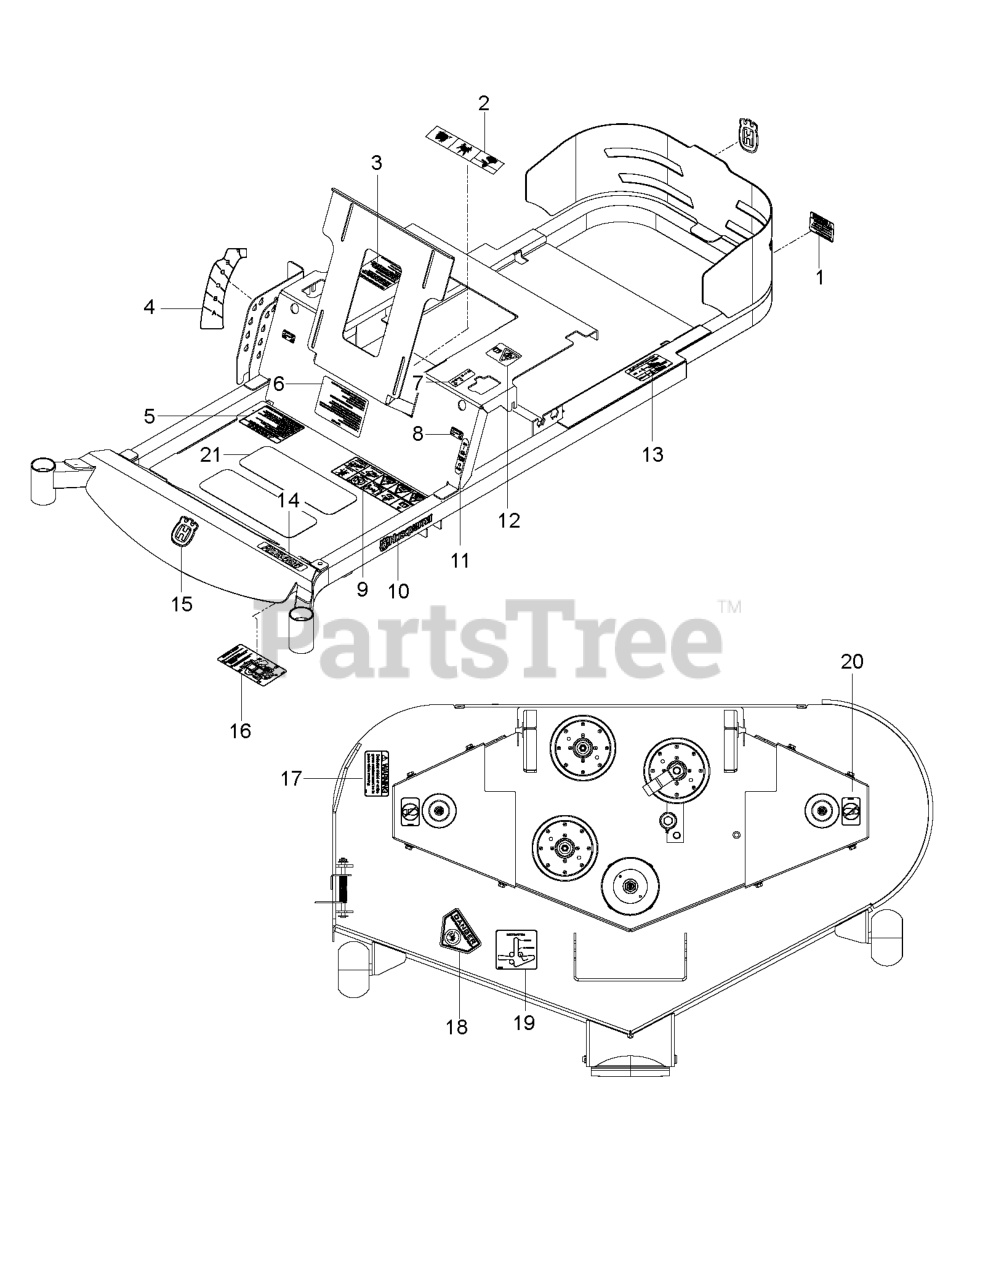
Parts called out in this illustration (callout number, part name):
1	DECAL, PROP. 65
2	EURO DECAL-BATTERY WARNIN6
3	DECAL, CUSTOMER RESPNSIBILITY
4	DECAL, HEIGHT
5	DECAL, WARNING
6	DECAL, START
7	DECAL, MOTION CONTROL
8	DECAL, F.S.T.
9	DECAL, SAFETY WARNING
10	DECAL.HOOD.LOGO.ORANGE.HUSQVAR
11	DECAL, PARK BRAKE
12	DECAL, EXITING MOWER
13	DECAL, DO NOT TOW
14	DECAL, EZ4824
15	DECAL, CROWN H 70MM
16	DECAL, SERVICE
17	DECAL, CAUTION
18	DECAL, CPSC
19	DECAL, BELT ROUTING
20	DECAL, NO STEP
21	ANTI-SKID PAD
